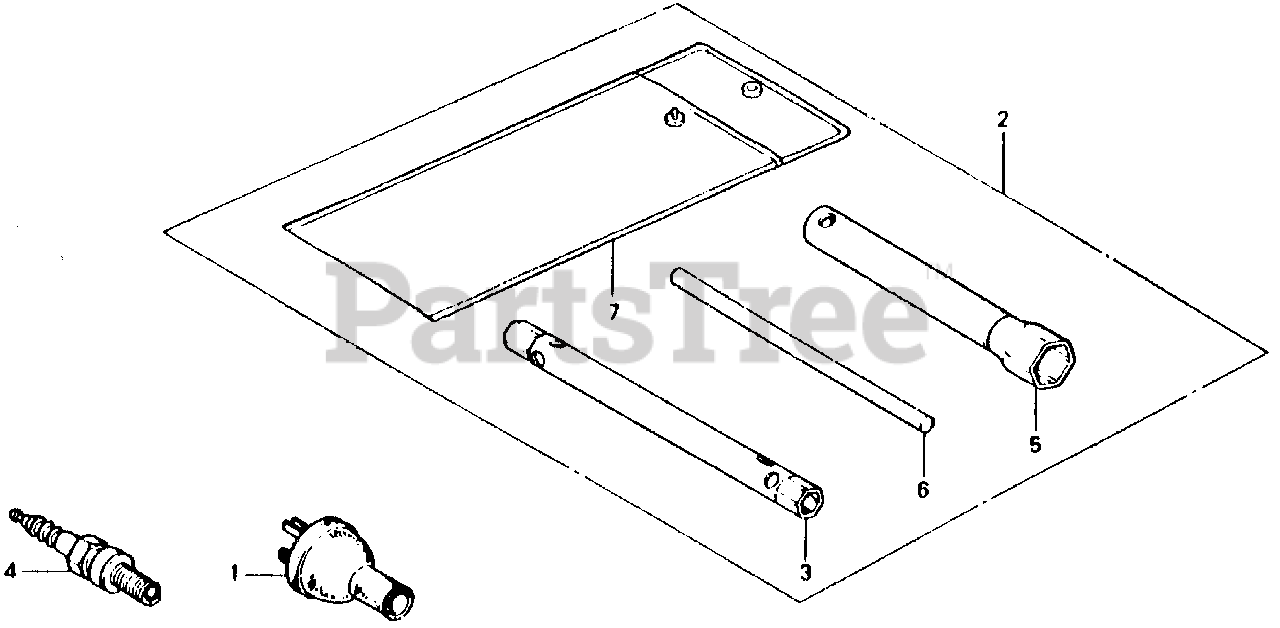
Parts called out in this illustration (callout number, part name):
1	PLUG (15A/125V)
2	TOOL KIT (NOT AVAILABLE)
3	WRENCH, BOX (10X12) (NOT AVAILABLE)
4	SPARK PLUG (BR-4HS) (NGK)
5	WRENCH, BOX (P21)
6	BAR A, HANDLE
